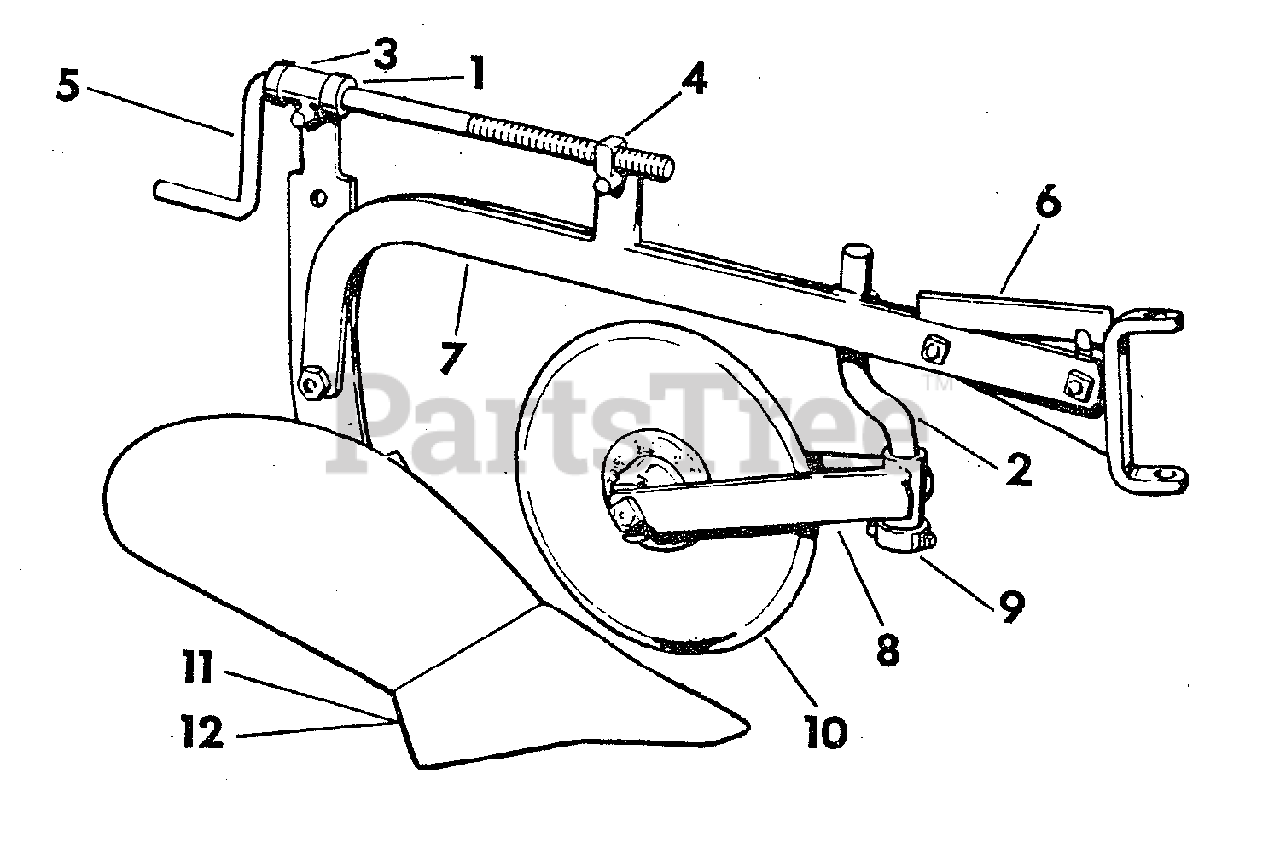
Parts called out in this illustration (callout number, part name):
1	COLLAR, Set
2	COULTER STANDARD
3	BEARING ASSEMBLY, Depth Screw
4	NUT ASSEMBLY, Adjusting, Depth Screw
5	DEPTH SCREW
6	END ASSEMBLY, Beam
7	BEAM ASSEMBLY, Plow
8	FORK ASSEMBLY, Coulter
9	STOP COLLAR, Coulter
10	COULTER, 10", Complete w/Bearings & Bolt
